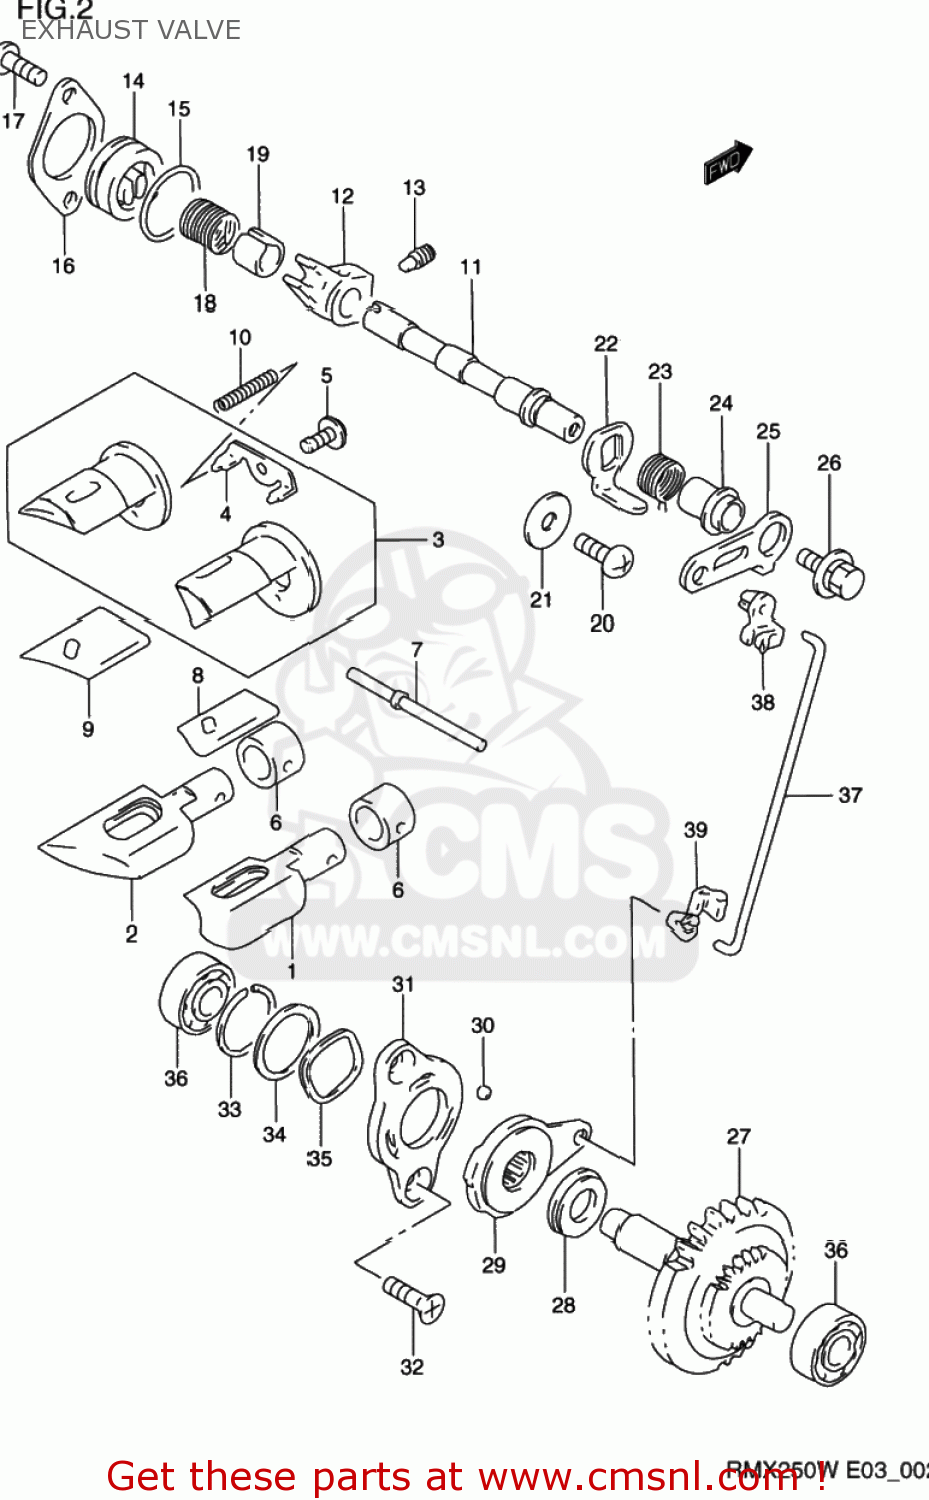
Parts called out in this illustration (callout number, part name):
1	VALVE,EXHAUST,LOWER,RIGHT
2	VALVE,EXHAUST LOW,L
3	GUIDE SET,EXHAUST VALVE
4	STOPPER,EXHAUST VALVE NO.2
5	SCREW 5X12
6	SPACER,EXHAUST VALVE
7	PIN,EXHAUST VALVE 48.5MM
8	VALVE,EXHAUST MIDDLE,R
9	VALVE,EXHAUST MIDDLE,L
10	SPRING
11	SHAFT,EXHAUST VALVE
12	ARM,EXHAUST VALVE SHAFT
13	SCREW(6X10)
14	CAP,EXHAUST VALVE
15	O RING(D:1.9,ID:22.6)
16	RETAINER,EXHAUST VALVE
17	BOLT
18	SPRING
19	SPACER,EXHAUST VALVE SPRING
20	BOLT
21	WASHER
22	LEVER,EXHAUST VALVE NO.2
23	SPRING
24	SPACER,EXHAUST VALVE
25	LEVER,EXHAUST VALVE NO.1
26	BOLT(5X12)
27	GOVERNOR ASSEMBLY,EXHAUST
28	BEARING(10X22X2.8)
29	ACTUATOR,EXHAUST VALVE
30	BALL
31	STARTER,EXHAUST VALVE ACTUATOR
32	SCREW(5X10)
33	CIRCLIP
34	SHIM(19.1X25X0.3)
35	WASHER
36	BEARING(8X22X7)
37	ROD,EXHAUST VALVE
38	BUSH,EXHAUST VALVE ROD NO.1
39	BUSH,EXHAUST VALVE ROD NO.2
